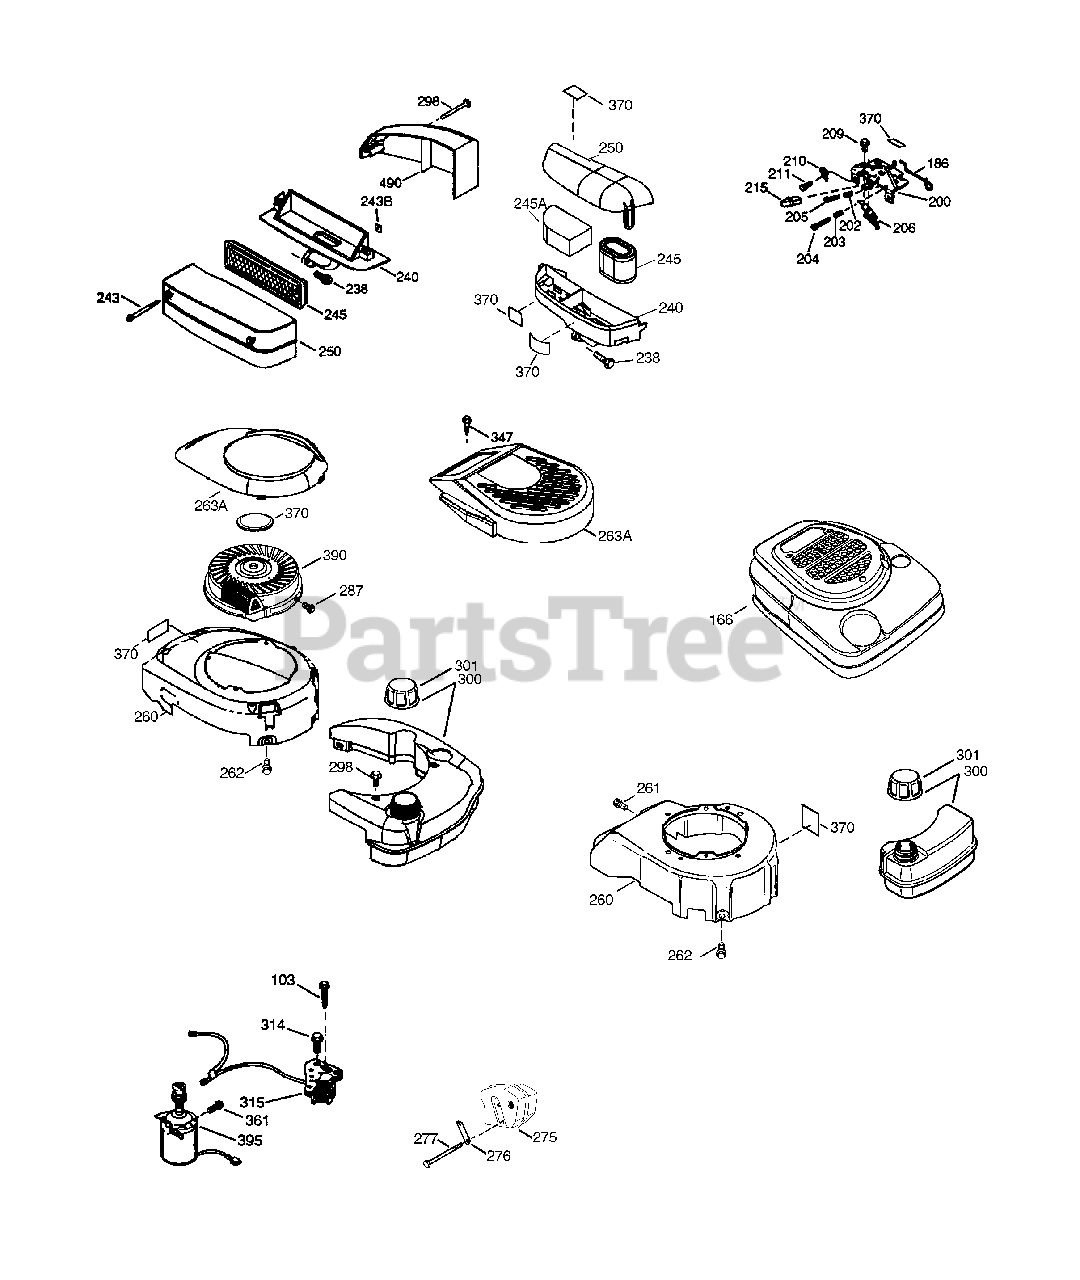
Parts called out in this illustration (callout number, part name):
86	Screw, 1/4-20 x 1-1/4"
103	Screw, T-15, 10-24 x 15/16"
186	Governor Link
200	Control Bracket
203	Compression Spring
204	Screw, T-10, 6-32 x 41/64"
204	Screw, T-10, 5-40 x 7/16"
206	Terminal
210	Conduit Clip
211	Screw, 10-32 x 3/8"
211	Screw, T-25, 10-32 x 5/8"
229	Nut & Lock Washer
238	Screw, 10-32 x 49/64"
245	Air Filter (Paper) (also available in Packaged Part #740083)
250	Air Filter Cover
260	Blower Housing
261	Screw, T-30, 1/4-20 x 1/2"
262	Screw, 1/4-20 x 1/2"
263A	Starter Grill
275	Muffler
276	Locking Plate
277	Screw, 1/4-20 x 2-47/64"
287	Screw, 8-32 x 21/64"
298	Screw, 10-32 x 35/64"
300	Fuel Tank (Incl. 292 & 301)
301	Fuel Cap
370	Decal - Tecumseh Logo for Top of Reco il Starter
370	Decal - Primer 3X with Hand
390	Rewind Starter NOTE: This engine cou ld havbeen built with 590702 starter.
999	Summer Maintenance Kit (incl. Oil, Sp ark Plug, Air Cleaner, & Ultra-Fresh)
